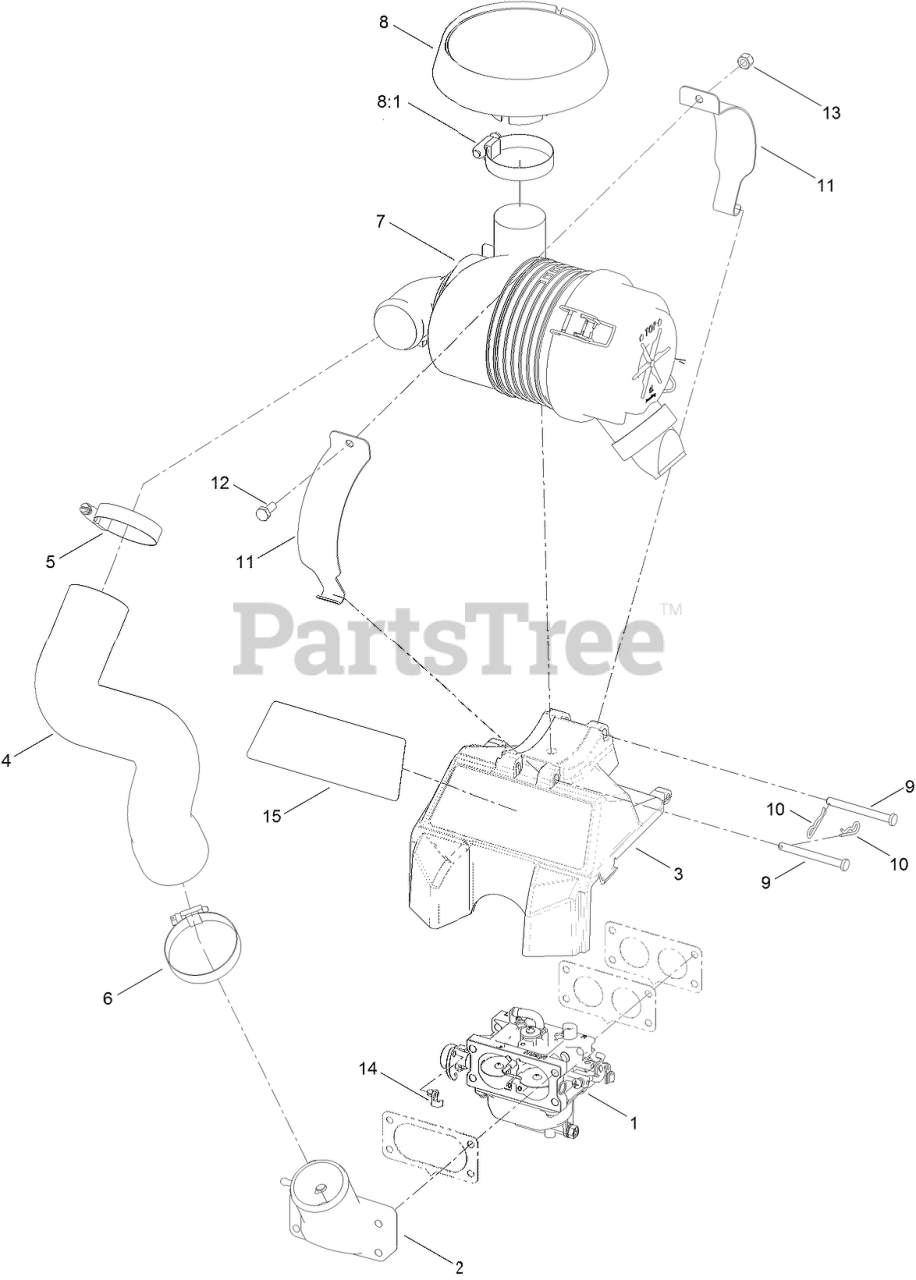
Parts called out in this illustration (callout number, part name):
1	CARBURETOR REPLACEMENT KIT ASM
2	MANIFOLD-INTAKE
3	SUPPORT-FILTER
4	HOSE-INTAKE
5	CLAMP-HOSE
6	CLAMP-HOSE
7	AIR CLEANER ASM
8	RAIN CAP KIT
8:1	CLAMP-HOSE
9	PIN-CLEVIS
10	PIN-COTTER
11	STRAP-CANISTER, AIR
12	SCREW-HH
13	NUT-HEX
14	CLIP-LINKAGE
15	DECAL-ENGINE 708 V-TWIN
